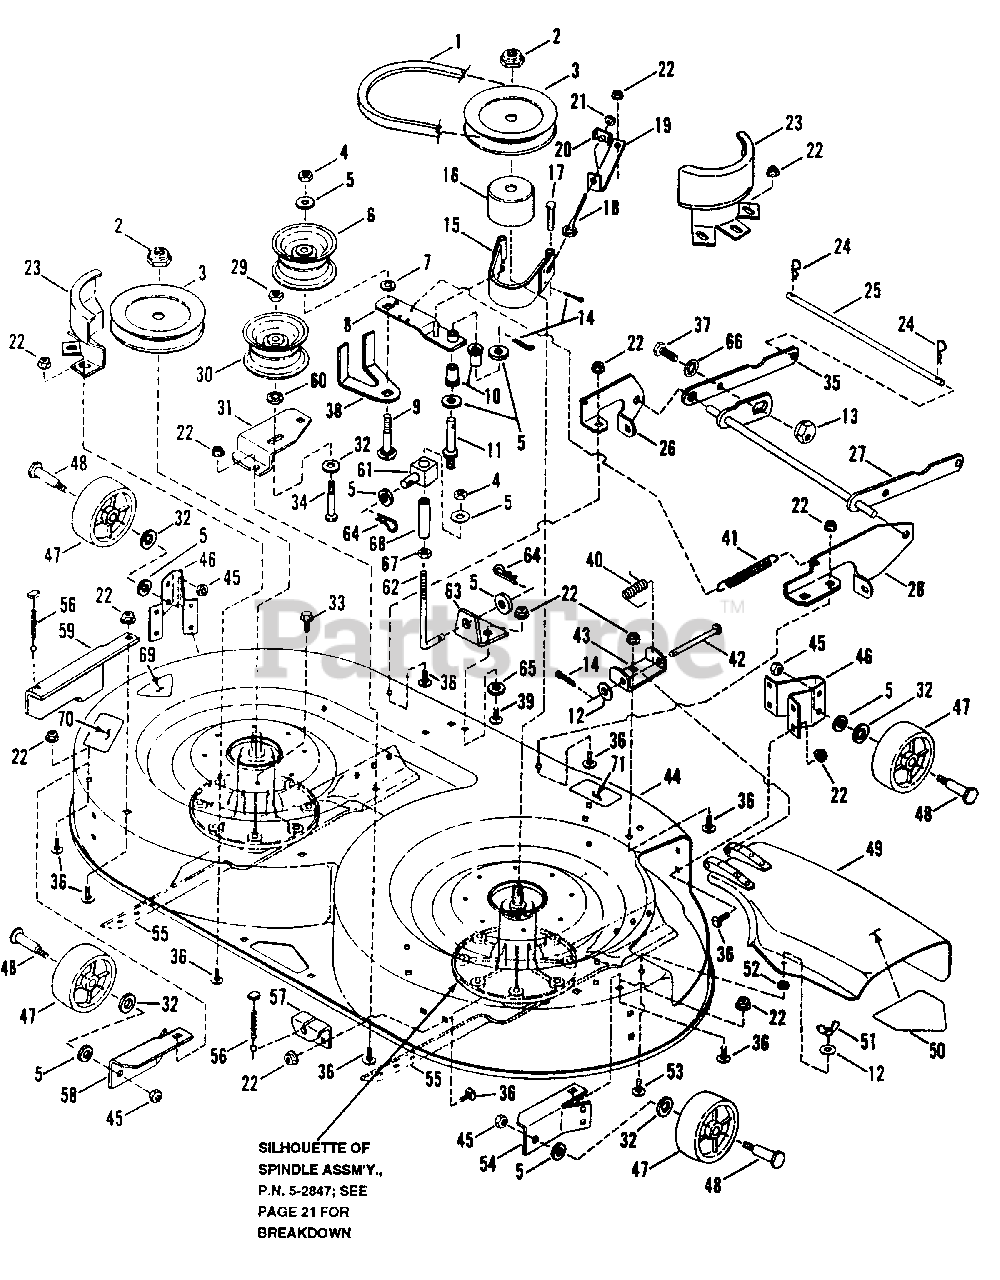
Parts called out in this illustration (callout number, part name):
1	BELT, Drive, 38' Cutting Deck, 98.25" EL
2	NUT, 5/8-18 Hex Nyloc
3	PULLEY, Spindle
4	NUT, 3/8-16 Hex Nyloc
5	WASHER, 3/8" Flat
6	PULLEY, idler
7	RETAINER, 3/8 Bolt
8	ARM, Idler Pulley
9	BOLT, 3/8-16 x 2 3/4" Short Neck Carriage, Grade 5
10	BUSHING, Flange
11	STUD, Idler
12	WASHER, Flat
13	ECCENTRIC, Leveling
14	COTTER-PIN, 3/32 x 3/4"
15	ASSEMBLY, Brake Band
16	DRUM, Brake
17	PIN, 1/4 x 1 5/8" Clevis
18	BOLT, 1/4-20 Eye
19	ANCHOR, Blade Brake
20	NUT, 1/4-20 "T" Lock
21	NUT, 1/4-20 Hex
22	NUT, 5/16-18 Hex Flange Lock
23	GUARD, Belt
24	PIN, Hair
25	PIN, Deck Hanger
26	BRACKET, Front Lift Arm (Left Side)
27	LIFT, Front Arm
28	BRACKET, Front Lift Arm (Right Side)
29	NUT, 1/2-13 Hex Nyloc
30	PULLEY, Idler
31	BRACKET, Idler
32	WASHER, 1/2 Flat
33	SCREW, 3/8-16 x 3/4" Self-Tapping
34	BOLT, 1/2-13 x 3" Hex Head Cap
35	ARM, Front Lift
36	BOLT, 5/16-18 x 1/2" Short Neck Carriage
37	BOLT, 3/8-24 x 3/4" Hex Head
38	GUIDE, Belt
39	BOLT, 5/16-18 x 3/4" Short Neck Carriage
40	SPRING, Chute Deflector Hinge
41	SPRING, Blade Brake
42	PIN, 5/16 x 3 3/16" Clevis
43	HINGE, Chute Deflector
44	DECK, 38' Cutting
45	NUT, 3/8-24 Hex Lock
46	BRACKET, Gage Wheel, Front
47	WHEEL, Gage
48	BOLT, 3/8-24 Shoulder
49	ASSEMBLY, Chute Deflector
50	DECAL, DANGER
51	NUT, 5/16-18 Wing
52	RETAINER, 5/16 Bolt
53	BOLT, 5/16-18 x 3/4 Short Neck Carriage, Grade 2
54	BRACKET, Wheel, Right Side
55	BLADE, 19-1/2"
56	CABLE, Rear Lift, 5.62"
57	BRACKET, Rear Deck Lift (Right Side)
58	BRACKET, Wheel (Left Side)
59	BRACKET, Rear Deck Lift (Left Side)
60	RETAINER, 1/2" Bolt
61	SWIVEL, Lift
62	BOLT, "J"
63	BRACKET, Angle (Front)
64	PIN, Hair
65	WASHER, 7/16 Flat
66	WASHER, 3/8 Internal Tooth Lock
67	NUT, 3/8-16 Hex
68	SPACER, Lift
69	DECAL - 38 Inch
70	DECAL - CAUTION (Rotating Blades)
71	DECAL - CAUTION
